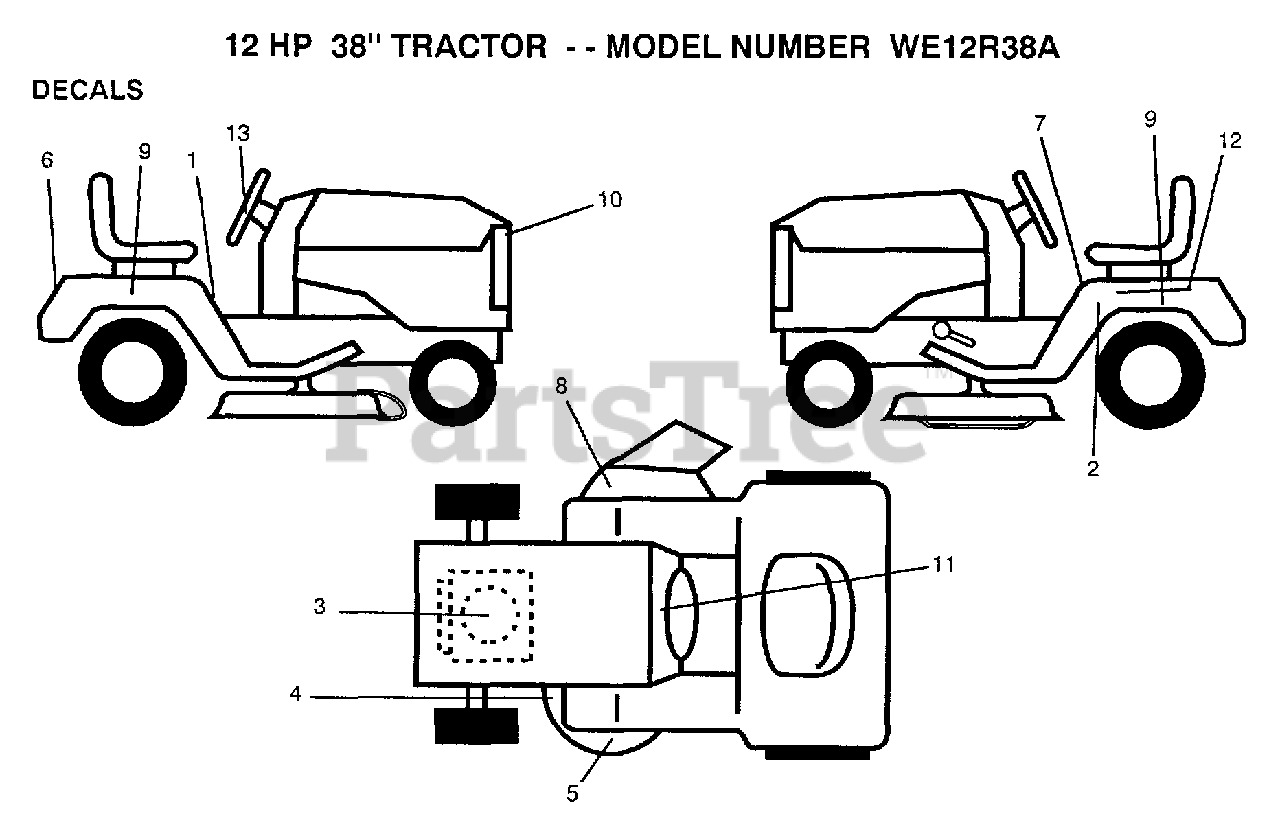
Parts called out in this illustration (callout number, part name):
1	DECAL.SHIFT.CTR.
2	IND HGT DECK DECA
4	DECAL
6	DECAL.FENDER
7	DECAL CAUTION
8	"DECAL, WARNING"
9	DECAL.FEND.QUICKS
10	"DECAL,LIGHT BOX"
12	DECAL
13	DECAL.WHL.STRG.
